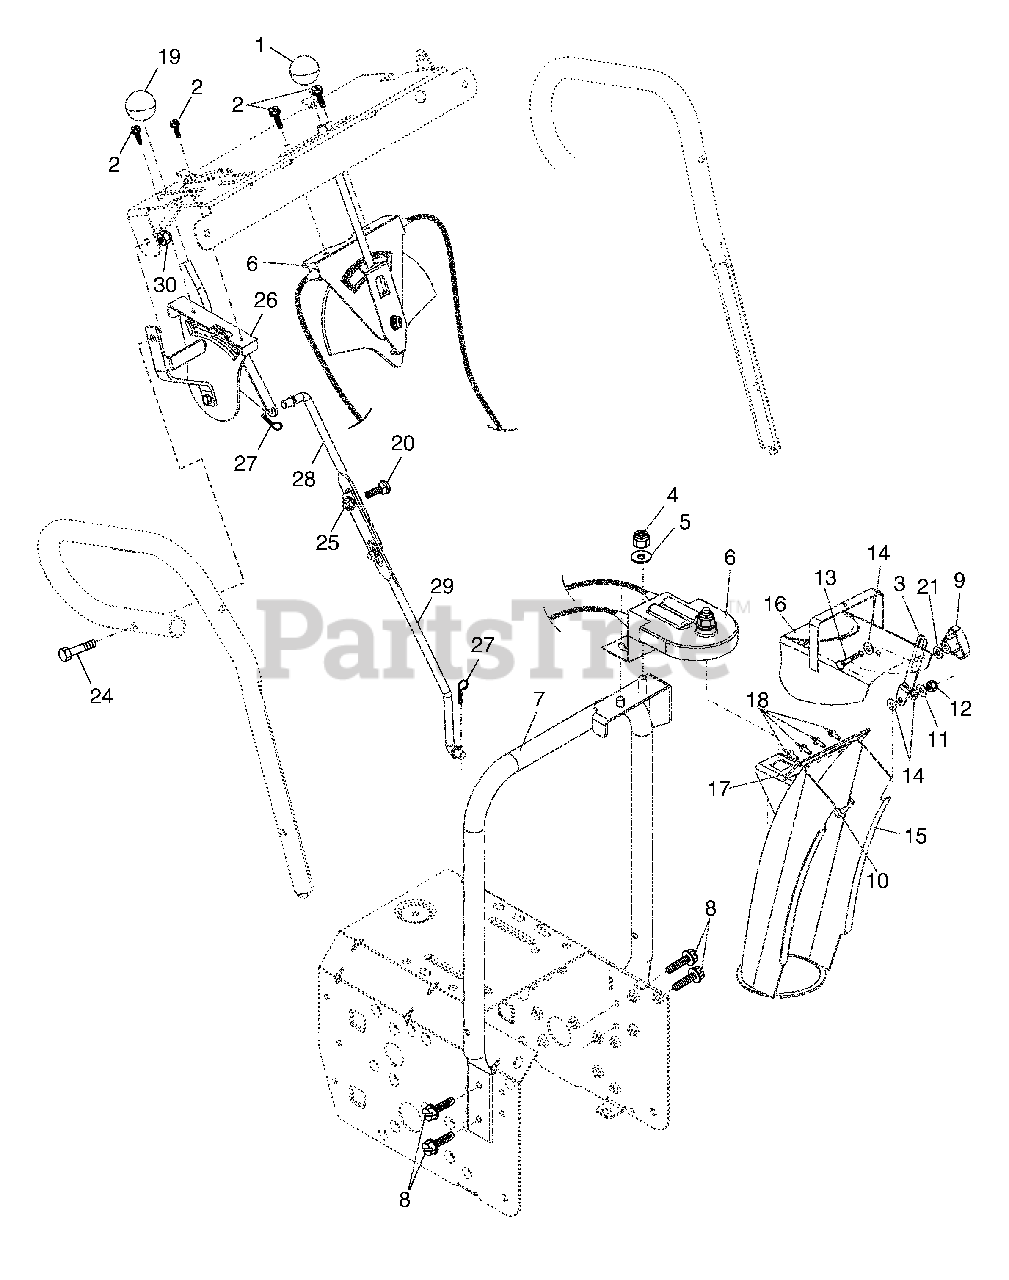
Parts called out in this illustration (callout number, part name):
1	Knob, Lever
2	Screw #10-24 x 5/8
3	Strap, Slotted
4	Nut, Lock 3/8-16
5	Washer, Flat 3/8
6	Control Assembly, Chute Rotater
7	Support, Pivot
8	Screw, Hex Head 5/16-18 x 3/4
9	Knob, Deflector
10	Bolt, Shoulder
11	Washer, Flat 1/4
12	Nut, Lock 1/4-20
13	Bolt, Carriage 5/16-18 x 5/8
14	Washer, Nylon
15	Chute Assembly
16	Deflector Assembly
17	Seal, Deflector
18	Rivet, Blind
19	Knob, Speed Control Lever
20	Bolt, Carriage 5/16-18 x 3/4
21	Washer, Flat
24	Screw, Hex Head 5/16-18 x 1-3/4
25	Nut, Lock 5/16-18
26	Lever Assembly, Speed Control
27	Retainer, Hairpin
28	Rod, Upper, Speed Control
29	Rod, Lower, Speed Control
30	Locknut, Hex 5/16-18
